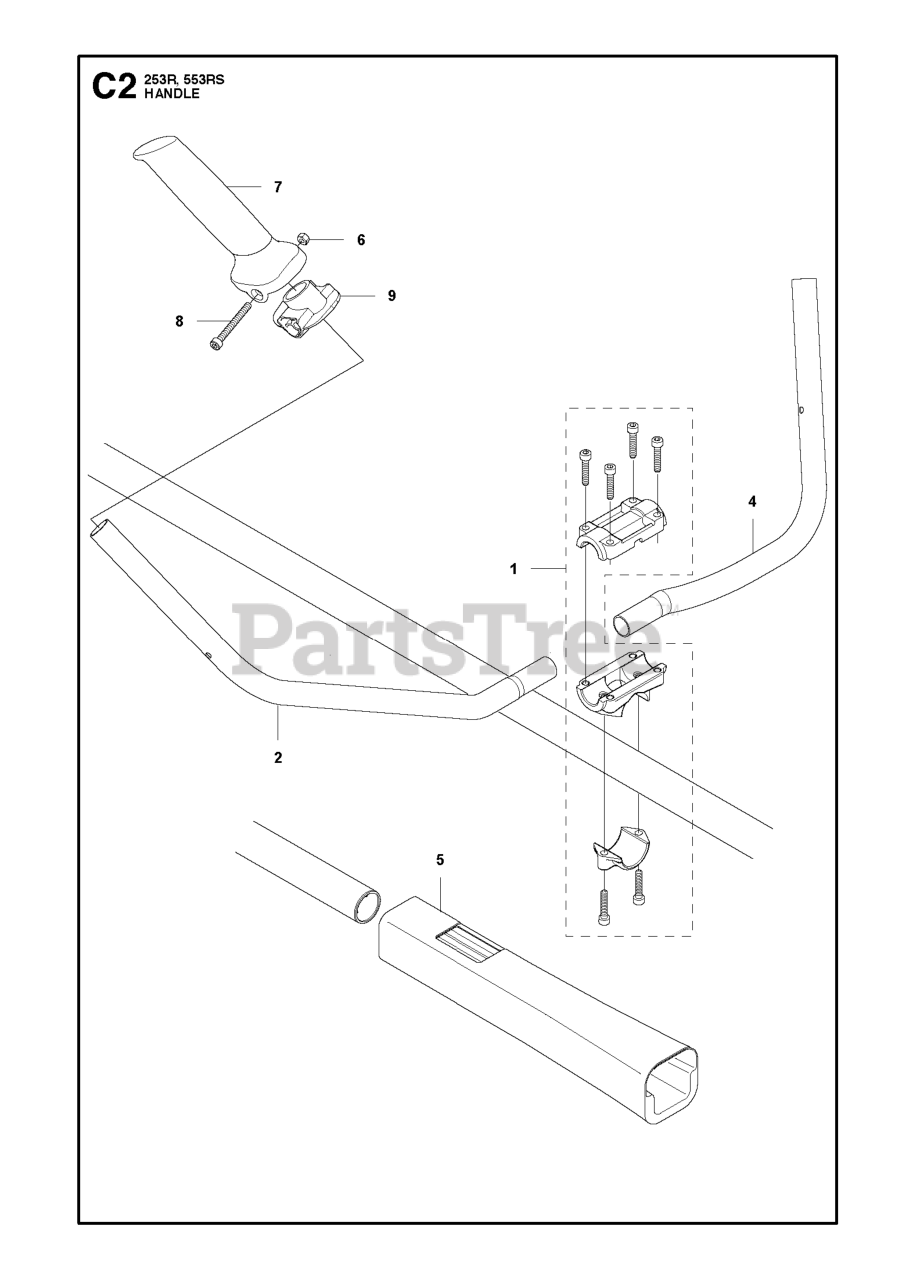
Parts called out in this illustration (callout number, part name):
1	HANDLE BRACKET ASSY 243R
5	PROTECTOR (RPLS 405017110)
6	NUT
